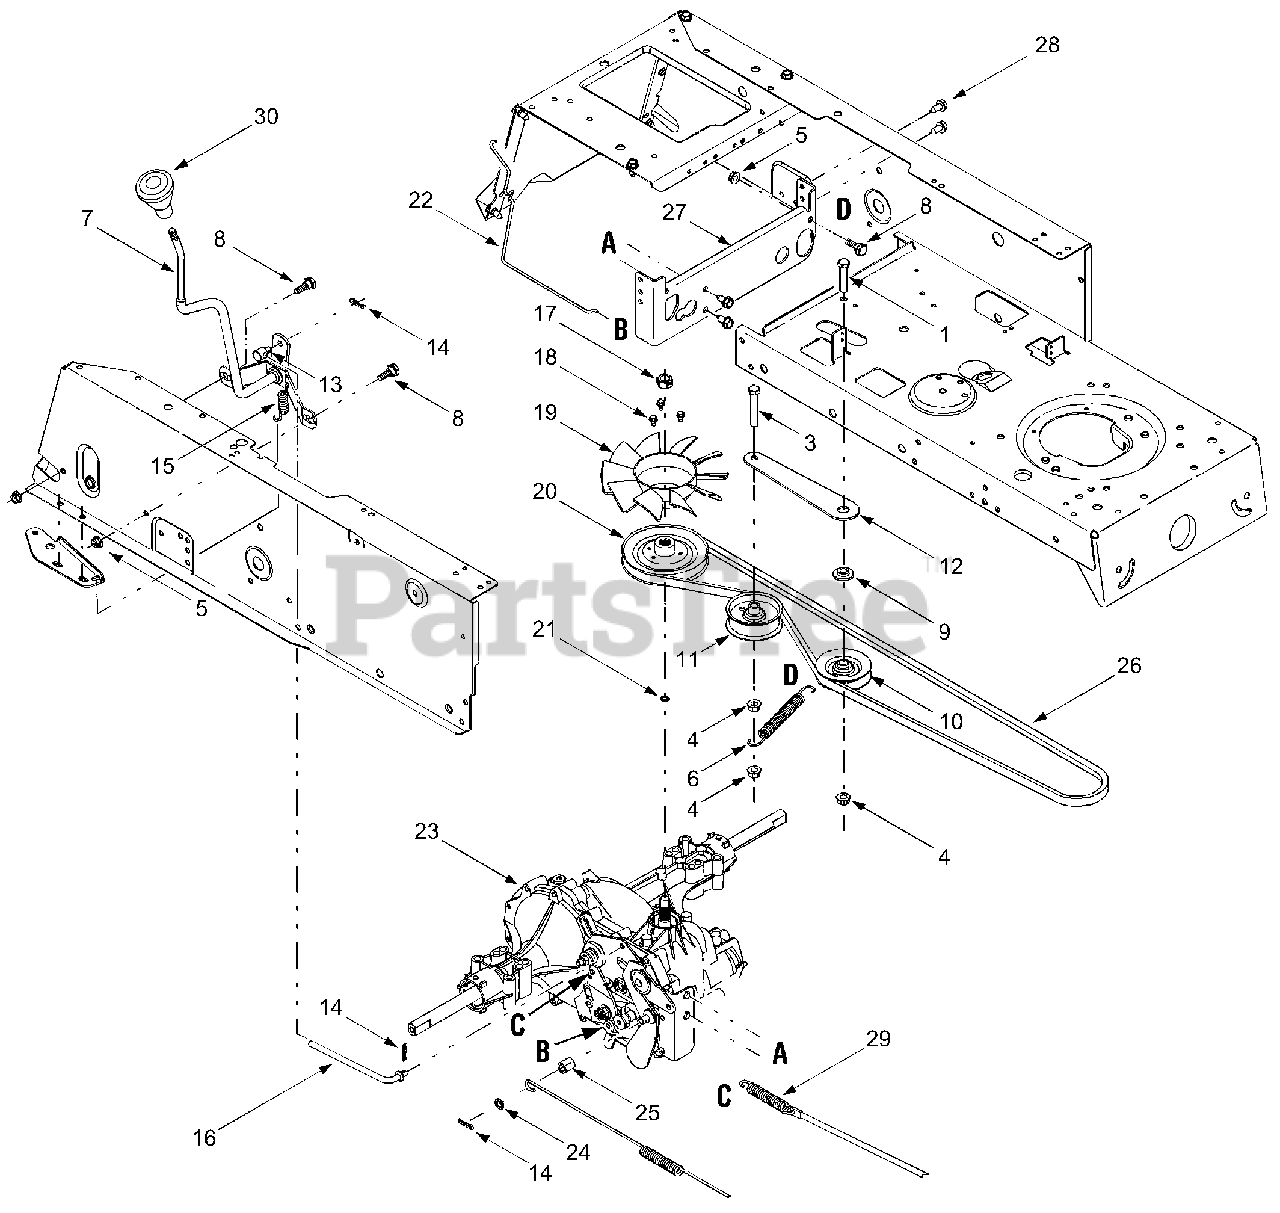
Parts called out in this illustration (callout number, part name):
1	Hex Screw, 3/8-16 x 1.75
2	Hex Screw, 5/16-18 x .75
3	Hex Screw, 3/8-16 x 2.25
4	Flange Lock Nut, 3/8-16
5	Lock Nut, 5/16-18
6	Extension Spring, .62 x 6.38
7	Hydro Speed Selector
8	Shoulder Screw, .437 x .286
9	Shoulder Spacer, .625 x 1.16
10	V-Type Idler Pulley, 3.06
11	Flat Idler Pulley, 2.75
14	Cotter Pin
15	Extension Spring, .50 x 2.54
16	Hydrostatic Control Rod
17	Hex Lock Nut, 1/2-20
18	Screw, #12-24 x .375
19	Fan Blade, 10
20	Transmission Pulley, 5.0
21	Ring Wire
22	Hydrostatic Bypass Rod
23	Hydrostatic Transmission
24	Flat Washer, .385 x .62 x .063
25	Spacer, .385 x .625 x .700
26	Belt
29	Extension Spring, .59 x 4.0
